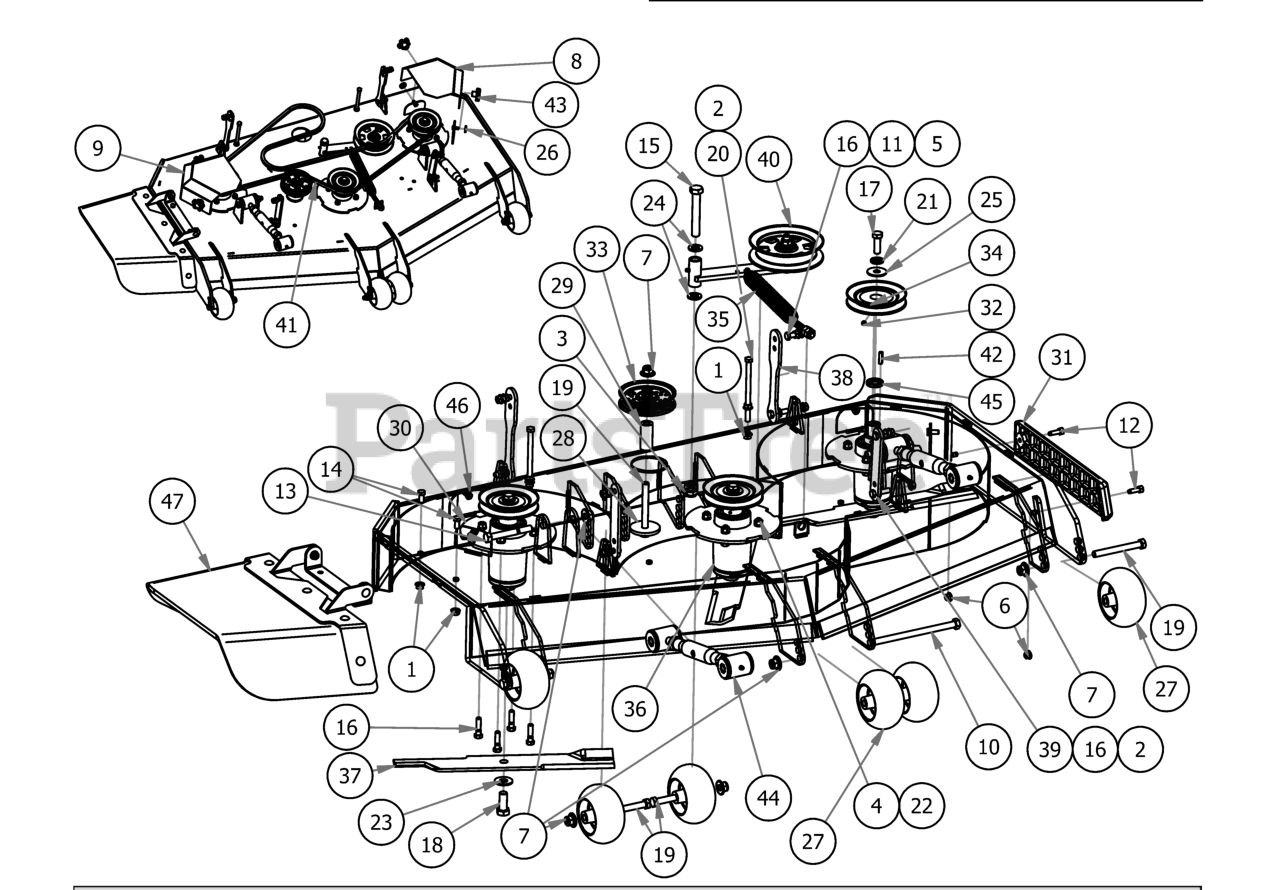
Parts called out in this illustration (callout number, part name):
1	3/8-16 HEX SERRATED FLANGE NUT HARD/ZINC
2	3/8" Nylock Flange Nut
3	5/8-11 Nylon Insert Jam Half Nut
4	3/8" Hex Nut
5	1/2" Hex Nut
6	5/16" Nylon Flange Nut
7	1/2-13 NYLON INSERT FLANGE LOCKNUT ZINC
8	2019 Stand On 54" Pulley Cover Trim
9	2019 Stand On 54" Pulley Cover Discharge
10	1/2-13 x 8 Hex Bolt Grade 5
11	All Thread-Pump Idler Tensioner
12	5/16-18 x 1 GR 5 Hex Bolt Zinc
13	1/2" x 4" Bolt (Grade 8)
14	3/8" x 3/4" Hex Bolt
15	5/8" x 4" Hex Bolt
16	3/8 x 1 1/2 Bolt
17	1/2"-20 x 1 1/2 - Grade 5 Fine Thread Bolt
18	5/8 x 1 1/2 Grade 8 Hex Bolt (Fine)
19	1/2-13 X 4-1/2 HEX CAP SCREW (GR.5) ZINC
20	3/8-16 x 5 1/2 Hex Bolt
21	1/2" Lock Washer Zinc
22	3/8" Lock Washer
23	5/8'' Flat Washer
24	.630 ID Plastic Washer
25	1/2" Belleville Washer
26	.360 ID X .983 OD X .120 THICK FLAT WASHER NYLON BLACK
27	2019 Deck Wheel
28	MZ Deck Idler Spacer
29	2019 Revolt Stationary Idle Spacer
30	Deck Spindle Support Plate
31	REVISED TRIM BUMPER_20180226
32	5/16 Set Screw
33	4 3/4 Idler Pulley - ABFI-76
34	5" Spindle Deck Pulley
35	2019 Outlaw Gen2 Deck Spring
36	Spindle Assembly
37	54" Deck Fusion Blade For Outlaw
38	2019 Stand-On Rear Deck Hanger
39	2019 Stand on deck hanger_front
40	2019 Revolt Deck Idler Assembly
41	42 inch Deck Belt- B120
42	1/4" x 1" Key
43	5/16" Knob
44	Turnbuckle
45	Spacer, 1x1.375x.25
46	2019 Stand On 54" Sloped Deck Welded Assemly
47	2019 Outlaw Gen2 Chute Assembly
